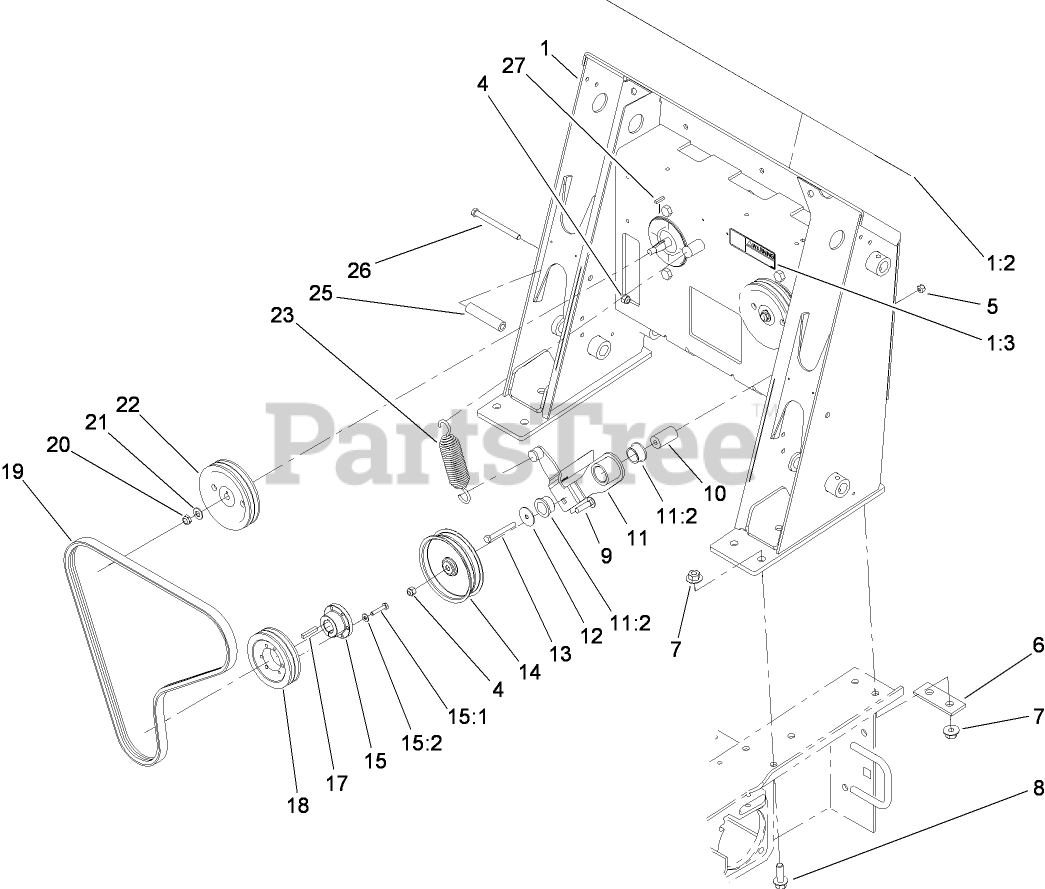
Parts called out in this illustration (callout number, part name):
1	LOADER TOWER ASM
1:2	DECAL-PANEL, CONTROL
1:3	DECAL-WARNING
4	NUT-LOCK, NI
5	NUT-LOCK, NI
6	PLATE-STIFFENER
7	NUT-LOCK, FLANGE
8	SCREW-HHF
9	SCREW-CARR
10	SPACER-MOUNTING
11	IDLER ARM ASM
11:2	BUSHING-FLANGE
12	WASHER-FLAT
13	SCREW-HH
14	PULLEY-IDLER
15	BUSHING
15:1	SCREW-HH
15:2	WASHER-LOCK
17	KEY-SQUARE
18	PULLEY
19	V-BELT
20	NUT-LOCK, NI
21	WASHER-FLAT
22	PULLEY
23	SPRING-EXTENSION
25	TUBE-SPACER
26	SCREW-HH
